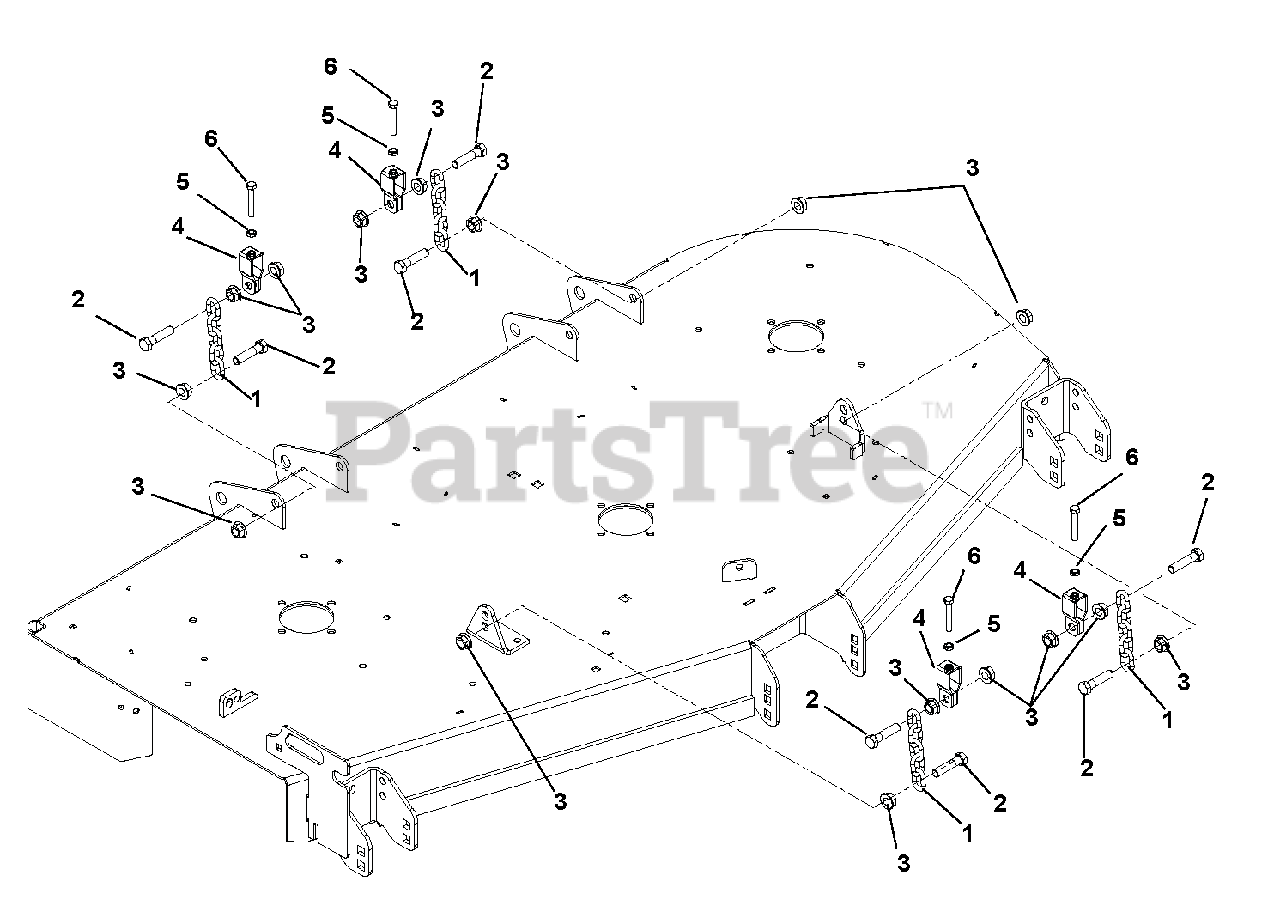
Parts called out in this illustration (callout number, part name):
1	CHAIN, LINK
2	BLT, HEX M12-1.75X50 CLS8.8 YZ
3	NUT-SPNLK-FLG M12-1.75 YZ
4	BRKT, DECK LEVELING
5	NUT- JAM .312-18 YWZC
6	BLT-HEX .312-18X2.00 FTH GR5YZ
